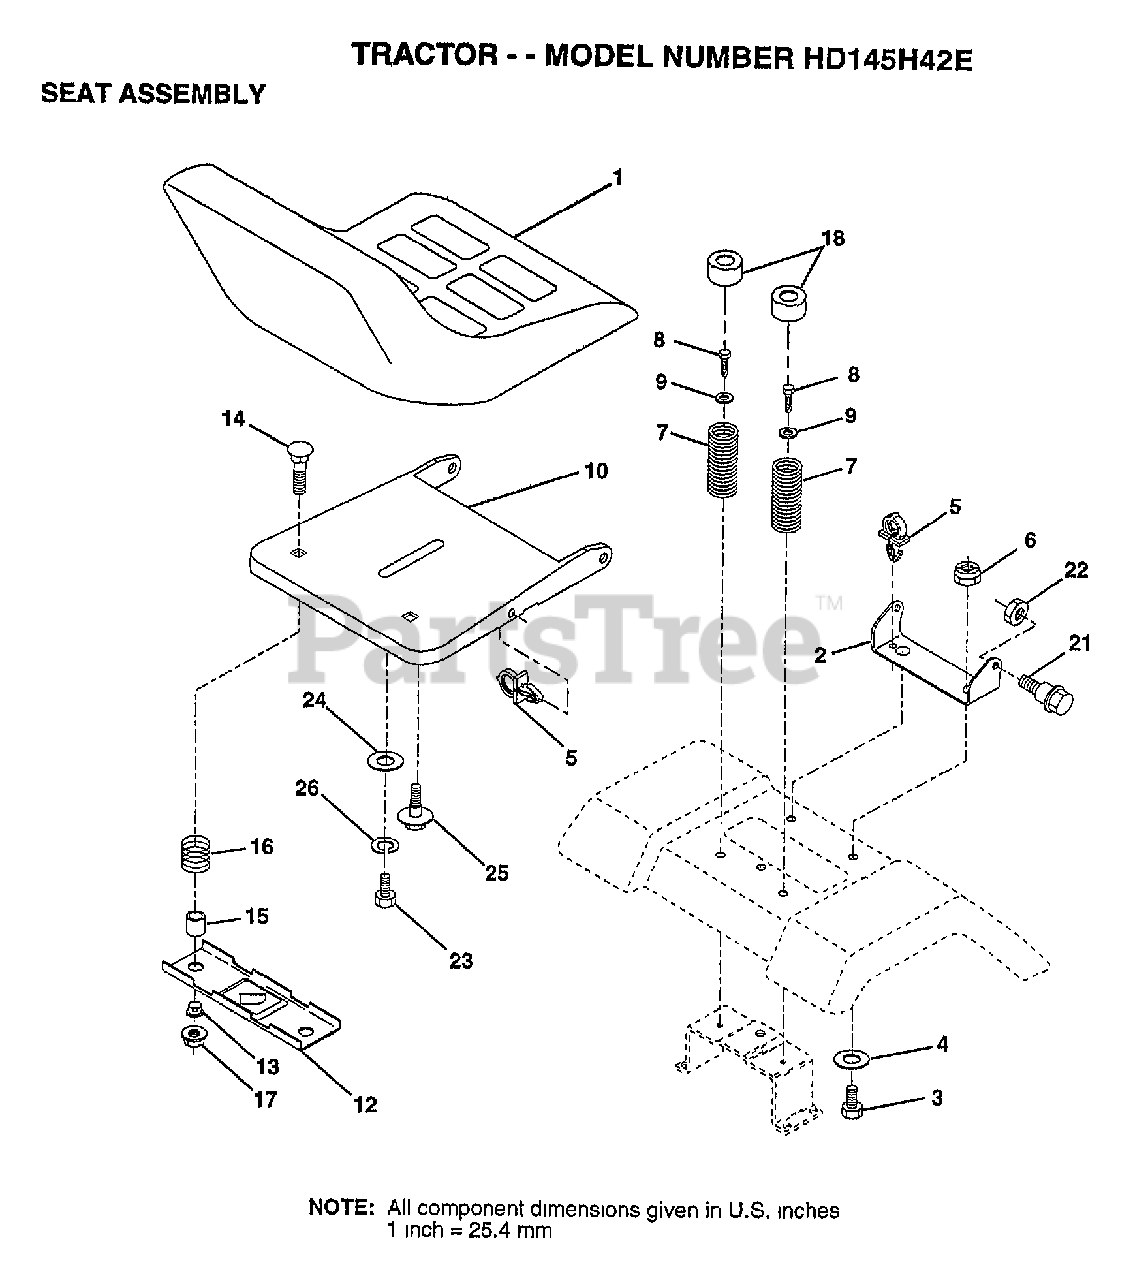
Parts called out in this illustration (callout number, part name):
1	SEAT
2	BRACKET PVT SEAT
3	BOLT
4	WASHER PM
5	CLIP.PUSH-IN.HING
6	NUT
7	SPRING COMPRESSIO
8	SCREW GTV
9	WASHER
10	PAN-SEAT
12	BRKT SWITCH
13	BUSHING
15	SPLIT SPACER
16	SPRING
18	CAP SPRING
21	"BOLT,SHOULDER"
23	BOLT
24	WASHER
25	"BOLT,SHOULDER"
26	LOCKWASHER
